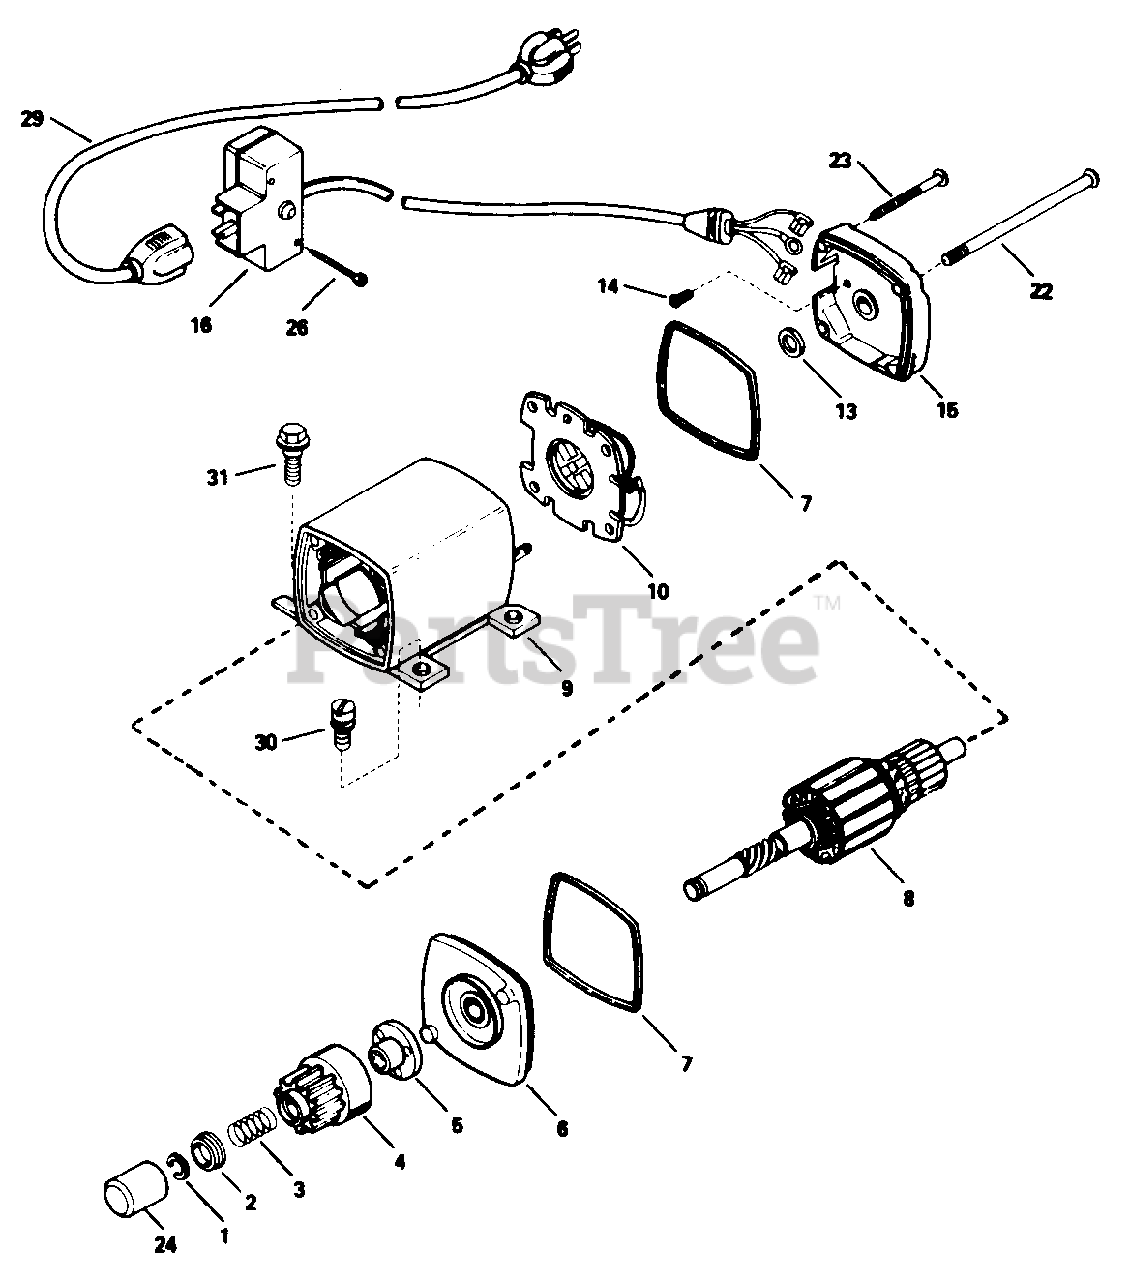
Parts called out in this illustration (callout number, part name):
1	Ring, Retainer
2	Retainer, Spring
3	Spring, Anti-drift
5	Nut and Retainer
6	Cap Ass'y., Drive End
9	Housing Ass'y.
10	Card Ass'y., Brush
13	Washer, Thrust
14	Screw, Ground
15	Cap Ass'y., Commutator End
16	Box Ass'y., Switch
22	Bolt, Case
23	Screw, Grounding
24	Cover, Dust
26	Screw, Hex Hd. Self-Tap, 6-32 x 2-1/2
29	Cord, Extension
30	Screw, Fil. Hd. Sems, 1/4-20 x9/16
31	Screw, Hex Hd. Shoulder,1/420 x 1/2
